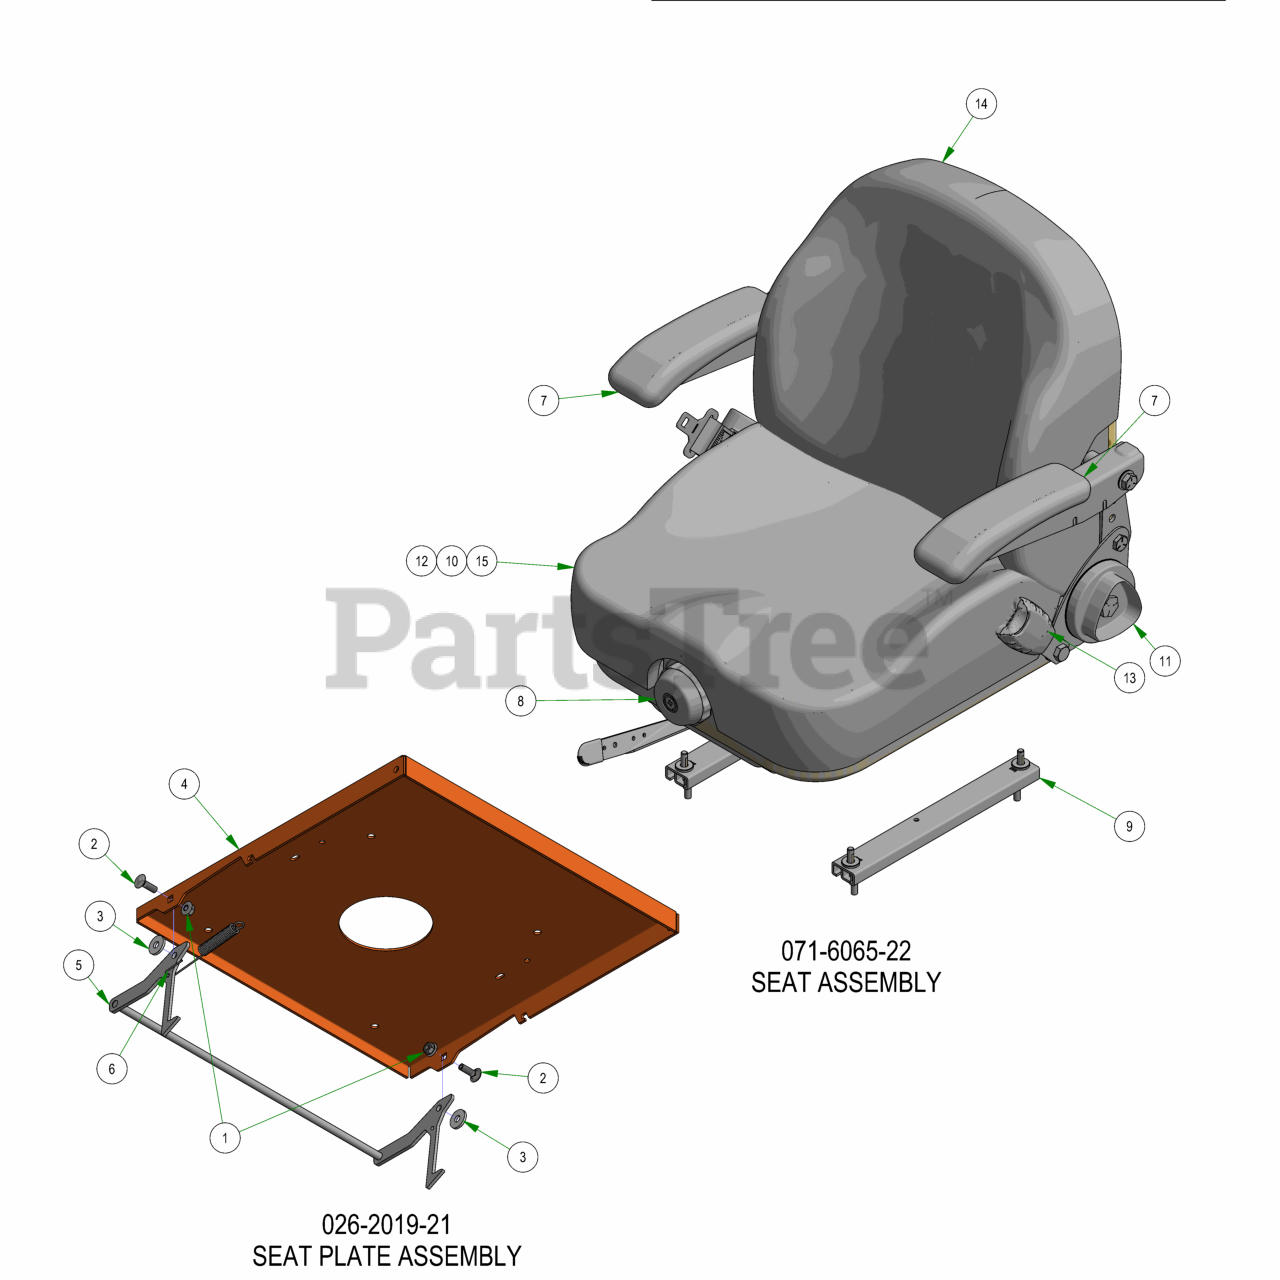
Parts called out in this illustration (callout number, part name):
1	5/16-18 NYLON INSERT FLANGE LOCKNUT ZINC
2	5/16-18 X 1 CARRIAGE BOLT (GR.8) ZINC
3	.360 ID X .983 OD X .120 THICK FLAT WASHER NYLON
4	R-SERIES SEAT PLATE
5	Seat Latch Rod Assembly
6	Brake Spring
7	Black Selfskin-Arm Pad Only
8	Weight Adjust Indicator Knob Assy
9	4" Single Locking Track Kit
10	Delta Plunger Switch - N.O.
11	Recliner Adjustment Knob-New
12	Bellows w/Hardware
13	2" Retractable Belt Kit w/Spacers
14	Back Cover for I3M - Recl - Logos
15	Cushion Cover Kit for I3M-Logo
